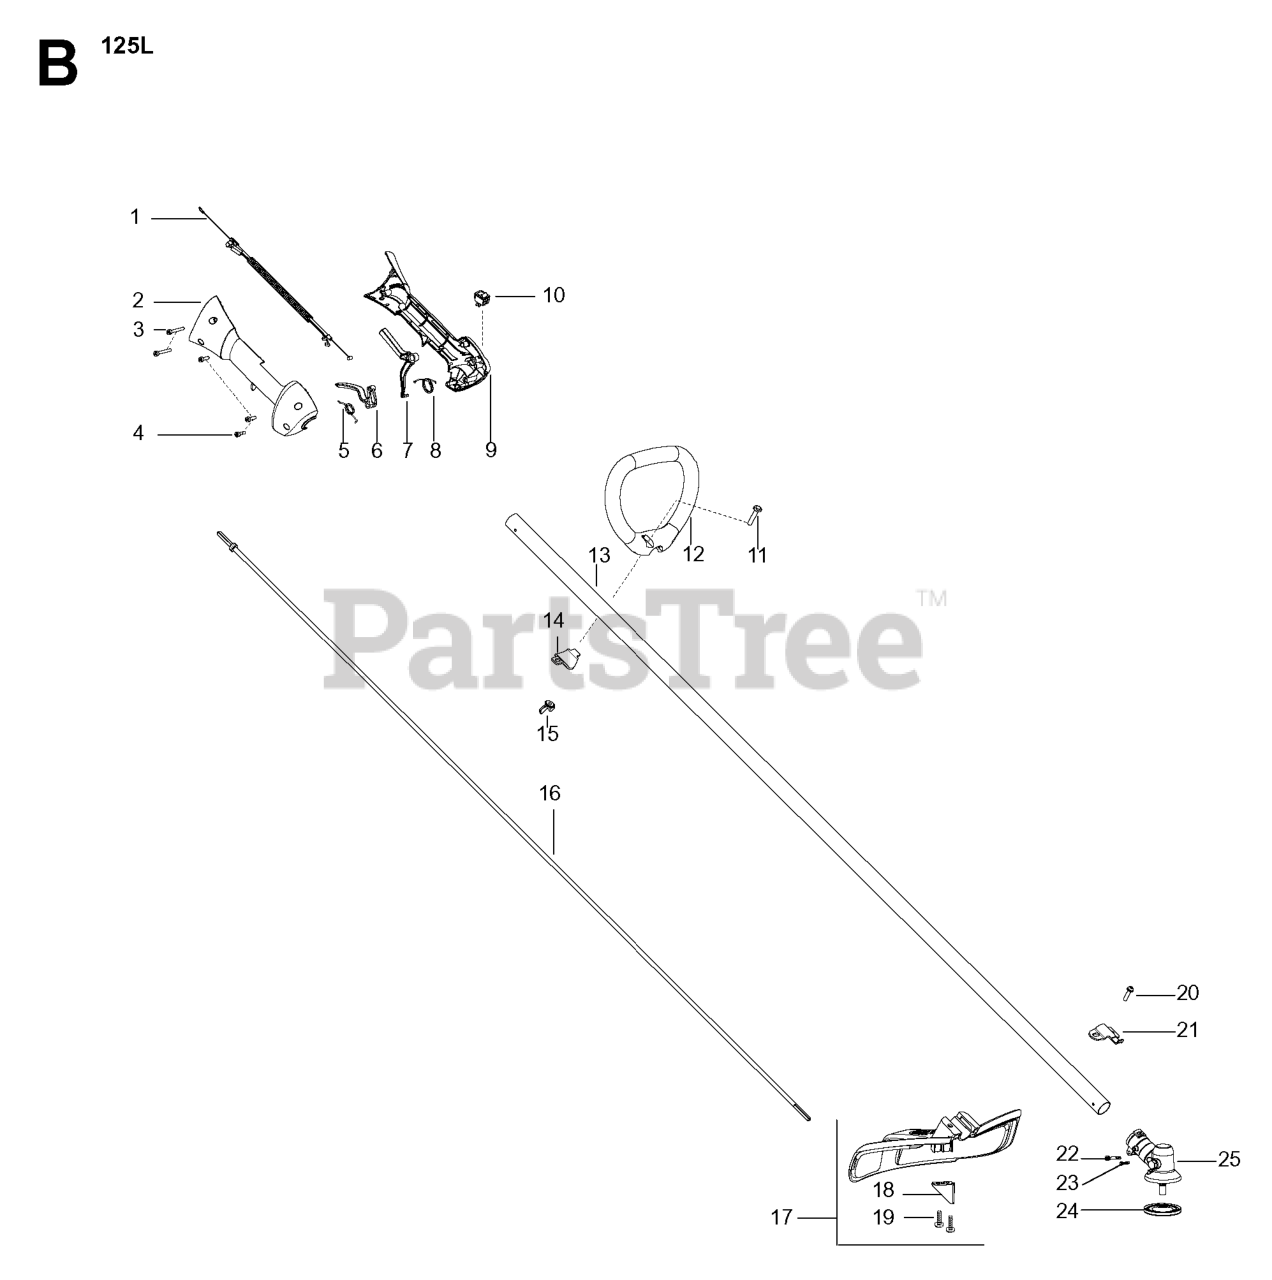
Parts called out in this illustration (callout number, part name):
1	%ASSY CABLE WIRE HARNESS
2	THROTTLE HSG RH
4	SCREW M4 X 1.75 PT 16MM
5	SPRING TRIGGER
6	TRIGGER
7	THROTTLE LOCKOUT
8	SPRING LOCKOUT
9	THROTTLE HSG LH
10	KIT SWITCH
11	BOLT, TYPE 2
12	HANDLE ASSIST
13	KIT DRIVESHAFT SST
14	CLAMP ASSIST HANDLE
15	WINGNUT, TYPE 2
16	FLEXSHAFT 57"
17	KIT COBI SHIELD
18	Limiter - Line
20	SCREW 1/4-20 X 7/8 (TAP
21	BRACKET SHIELD STRAIGHT SHAFT
22	SCREW - CARB. ADAPTOR
24	ASSY DUST CUP
25	ASSY GEARBOX
